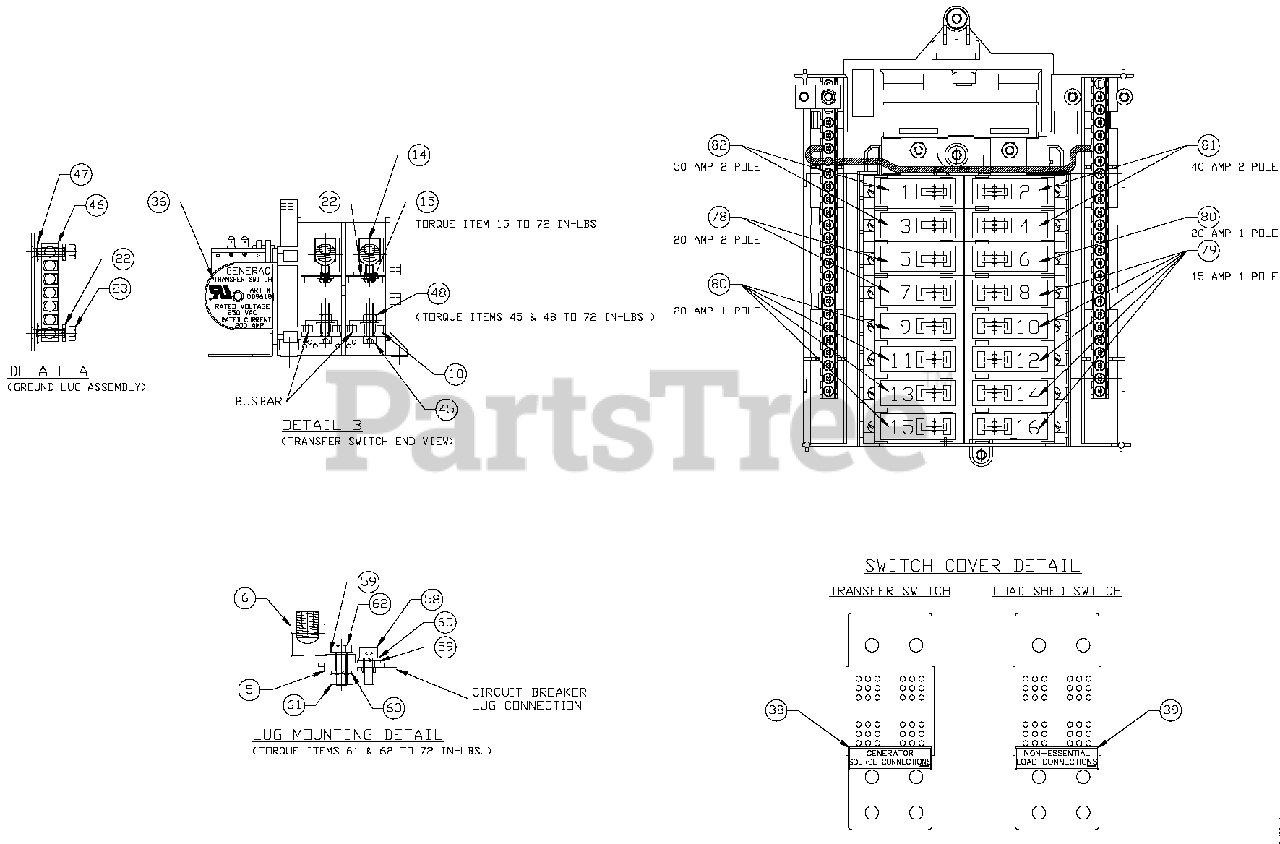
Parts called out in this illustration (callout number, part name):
5	BUSBAR, 200A LUG ADAPTER
6	LUG 300 MCM-6STR
10	BUSBAR, 200A TRANSFER SW T2
14	LUG SOLDERLESS 250-#6 AL/CU
15	SCREW BHSC 1/4-20 X 3/8
22	WASHER LOCK M6-1/4
23	NUT HEX 1/4-20 SS
38	DECAL, GENERATOR SOURCE
39	DECAL, NON-ESSENTIAL LOAD
45	BATTERY CHARGER ASSEMBLY
46	GROUND BAR (5) 2-14 AWG CONN
47	WASHER SHAKEPROOF EXT 1/4 STL
48	NUT HEX FL WHIZ 1/4-20
58	SCREW SHC M8-1.25 X 20 G8
59	WASHER FLAT 5/16-M8 ZINC
60	WASHER LOCK M8-5/16
61	NUT HEX M8-1.25 G8 CLEAR ZINC
62	SCREW HHC M8-1.25 X 25 C8.8
78	CB 0020A 2P PLUG IN
79	CB 0015A 1P PLUG IN
80	CB 0020A 1P PLUG IN
81	CB 0040A 2P PLUG IN
82	CB 0050A 2P PLUG IN
